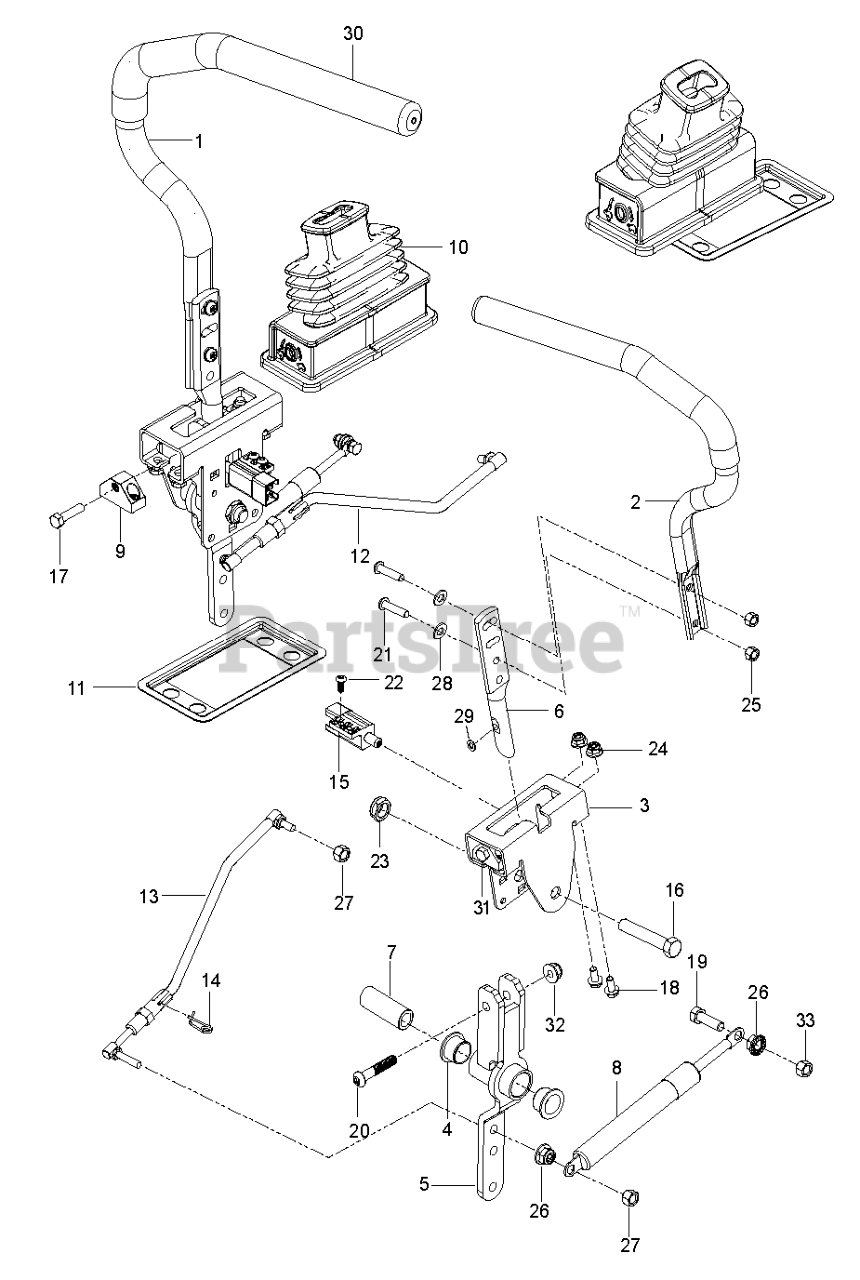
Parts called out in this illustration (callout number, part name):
1	TUBE RZ CONTROL LEVER RIGHT MS
1	TUBE.LEVER.CONTROL.ZTR.RT.428
2	TUBE.LEVER.CONTROL.ZTR.LT.428
3	BRACKET.CONTROLS.ZTR.X431
4	BEARING, FLANGE
5	LEVER CONTROL PIVOT
6	CONTROL.LEVER.HANDLE
6	Controls
7	SPACER.PIVOT.CONTROL
9	BLOCK TRACKING CONTROL ZTR
9	Blocks
10	BOOT.STEERING.LEVER
11	CONTROL.BOOT.FLANGE.X431
12	ROD.ASM.RH.ADJUSTABLE
12	Controls
13	ROD.ASM.LH.ADJUSTABLE
13	Rods
14	RETAINER.CLIP.SPRING.S
15	SWITCH.INTLK.RZ.RFRSH.BUTTON
16	Bolts
16	HCS 1/2-13 X 2-3/4 GD 5 ZD
17	SCREW.SHAKEPROOF.1.25.BLACK
18	Bolts
18	HHFS 5/16-18 X 3/4
19	HCS 5/16C X 1
19	Bolts
20	SCREW.CAP.SOCKET.6PT.5/16-18
21	BUTTONHEAD.5/16-18X1.125.BLACK
22	SCR #10-24 X .75 SKT HD BLK
22	SCREW.BUTTONHD.10-24X1/2.(2 2)
23	NUT 1/2-13 HEX JM NYL
24	NUT HEXAGON FLANGE 5/16-18 ST
24	5/16-18 NYLOC FLANGE NUT
25	NYLOCK.NUT.5/16-18 BLACK
25	Nuts
26	GSPW Hardware
26	NUT 5/16C WHIZ
27	Nuts
27	NUT.71038.31-18.HEX.NYLOCK
28	WASHER.11/32X11/16 BLACK
28	WASHER 11/32 X 11/16 X 14 GA T
28	WASHER
29	WASHER.11/32ID.11/16OD.116THIC
30	PURCHASE THE COMPLETE LEVER
31	SCREW.CAP.SOCKET.6PT.5/16-18
31	BUTTONHEAD.5/16-18X1.125.BLACK
32	NUT.71038.31-18.HEX.NYLOCK
32	5/16-18 NYLOC FLANGE NUT
32	NUT HEXAGON FLANGE 5/16-18 ST
33	5/16-18 NYLOC FLANGE NUT
